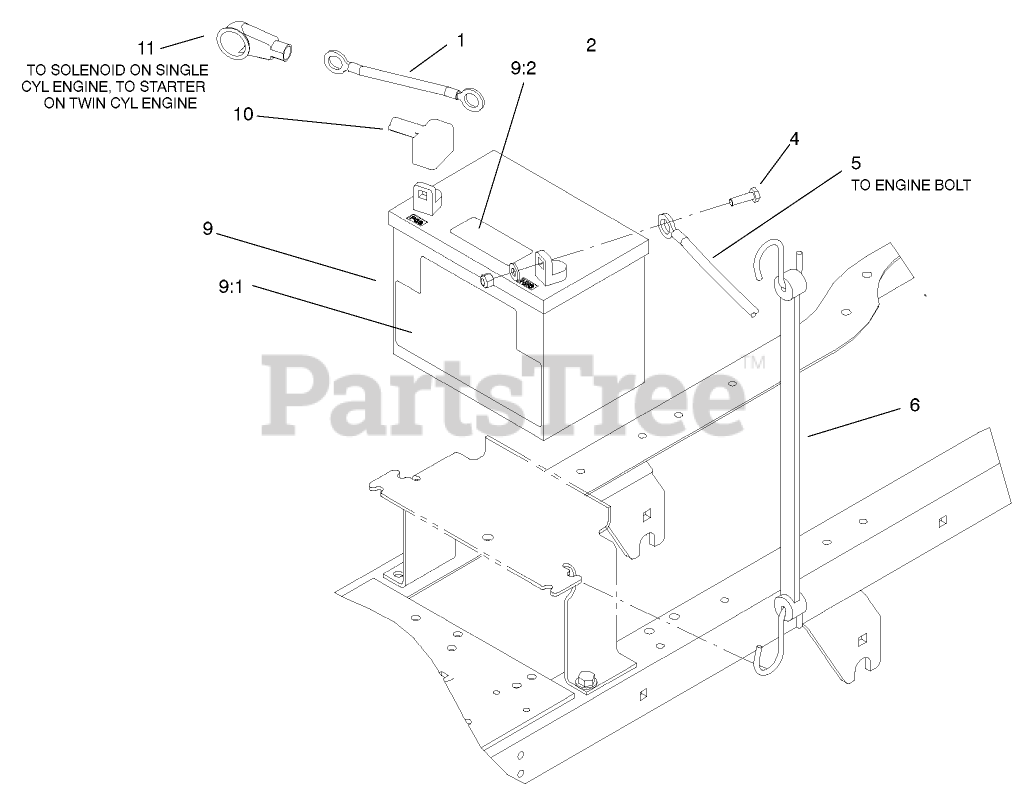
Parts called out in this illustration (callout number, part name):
1	WIRE-21 INCH
2	NUT-LOCK, NI
3	WASHER-FLAT
4	SCREW-HH
5	CABLE-BATTERY
6	HOLD-DOWN, BATTERY
9	BATTERY-DRY
9:1	Decal-Battery
9:2	Decal-Battery
10	BOOT-TERMINAL
11	BOOT-INSULATOR, TERMINAL
